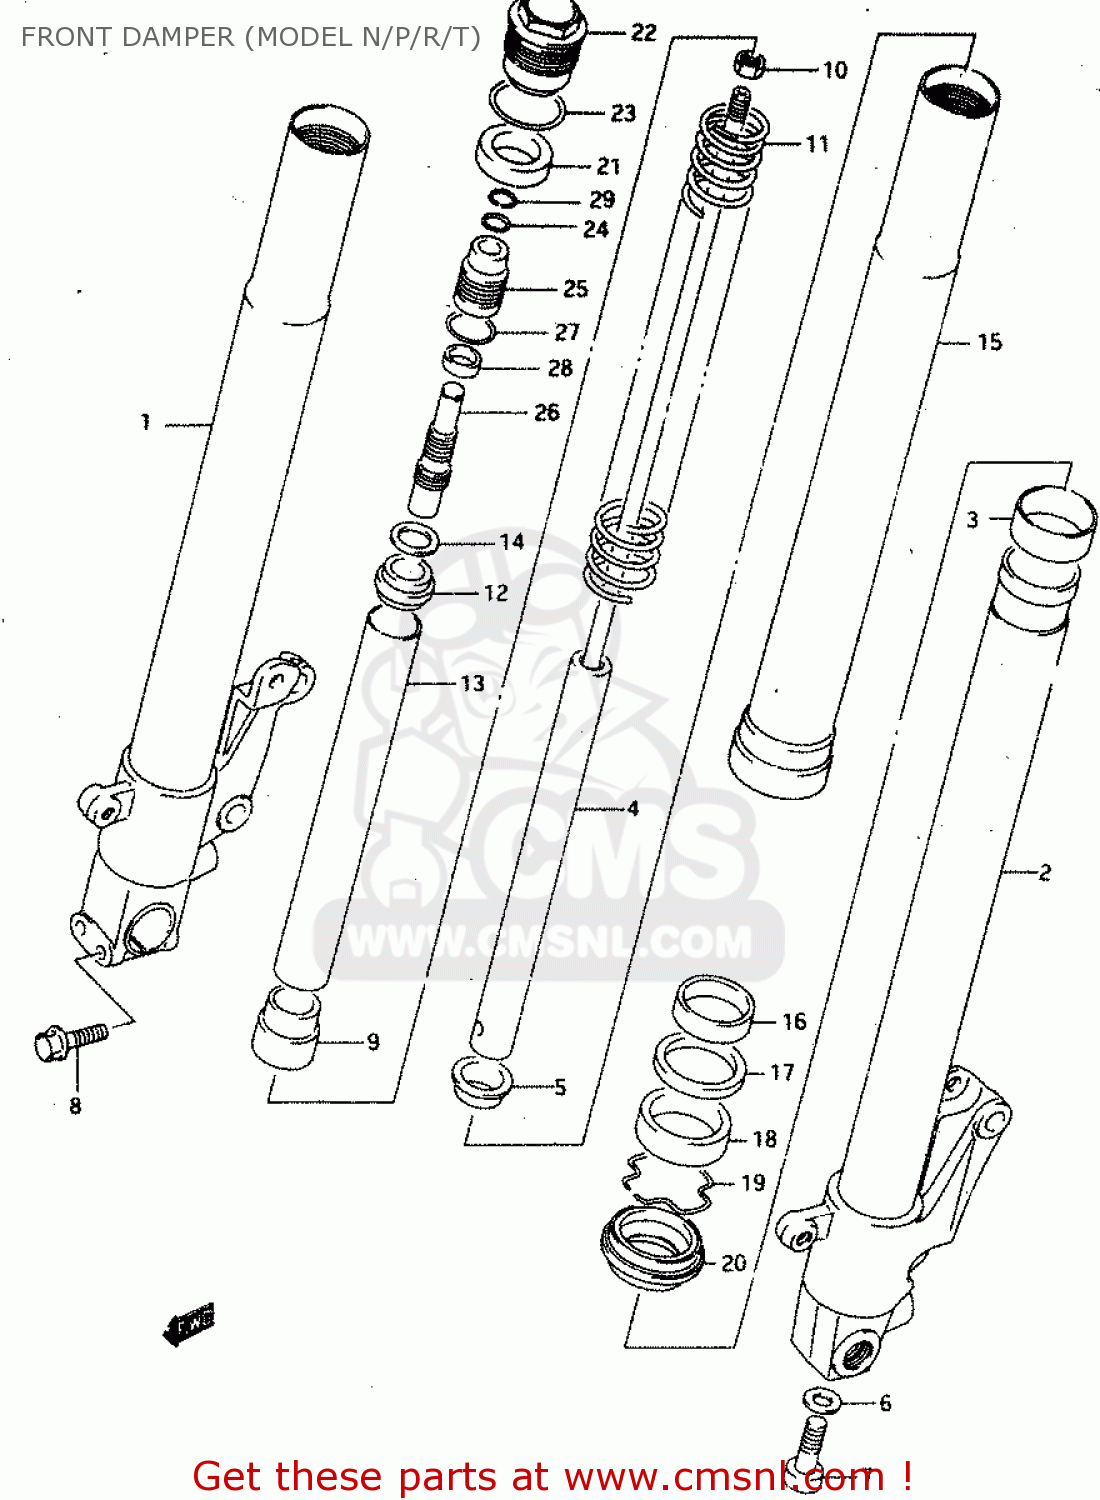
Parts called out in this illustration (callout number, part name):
1	TUBE,INNER,R
2	TUBE,INNER,L
3	BUSH,SLIDE
4	DAMPER,FR
5	PLATE,CENTERING
6	GASKET (NAS)
7	BOLT,CTR
8	BOLT
9	JOINT,SPRING UPR
10	NUT
11	SPRING,FR FORK(SP,SF)
12	GUIDE,SPRING UPR
13	SPACER,SPRING
14	GUIDE,SPRING
15	TUBE,OUTER
16	BUSH,GUIDE
17	SPACER,SEAL
18	SEAL,OIL
19	CIRCLIP,FORK OIL SEAL
20	DUST SEAL
21	RUBBER,SEAT
22	BOLT,FORK
23	O RING,FORK BOLT
24	O-RING (D:2.4 ID:13.8)
25	CASE,ADJUSTER
26	ADJUSTER,SPRING
27	O RING
28	PLATE,SPRING ADJUSTER
29	RING,STOPPER
